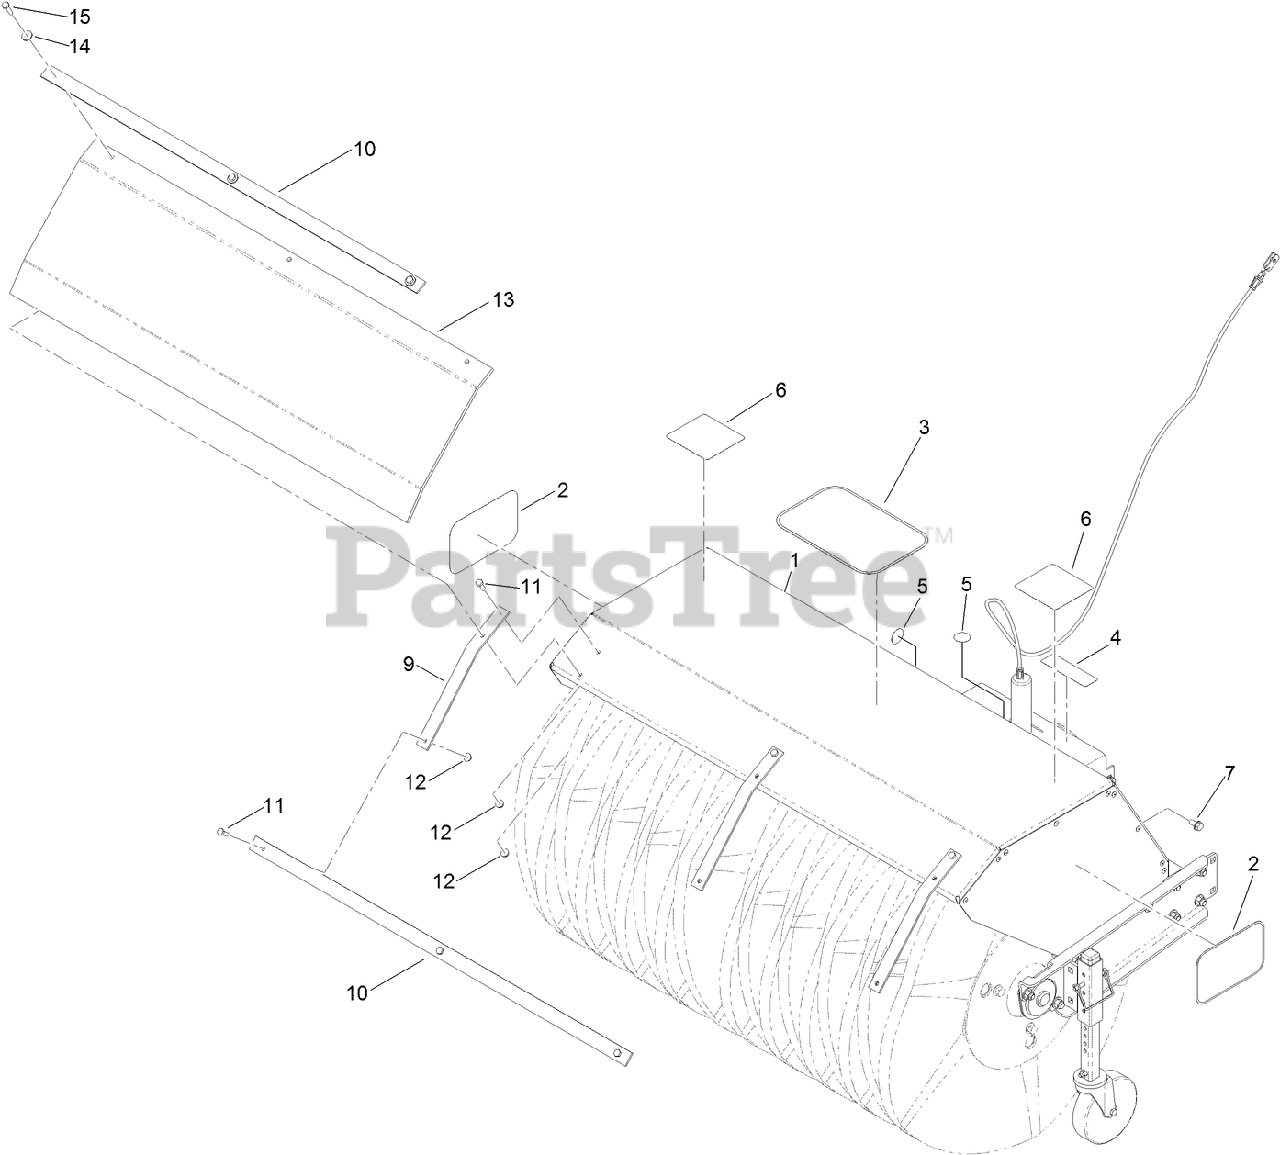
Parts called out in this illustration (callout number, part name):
1	BROOM ASM
2	DECAL
3	DECAL
4	DECAL-MISSING, COVER
5	DECAL-GREASE
6	DECAL-WARNING
7	SCREW-HWHTF
9	STRAP-SUPPORT, DEFLECTOR
10	STRAP-SUPPORT, BROOM DEFLECTOR
11	SCREW-HH
12	NUT-HF
13	DEFLECTOR-BROOM
14	WASHER-FLAT
15	SCREW-HH
